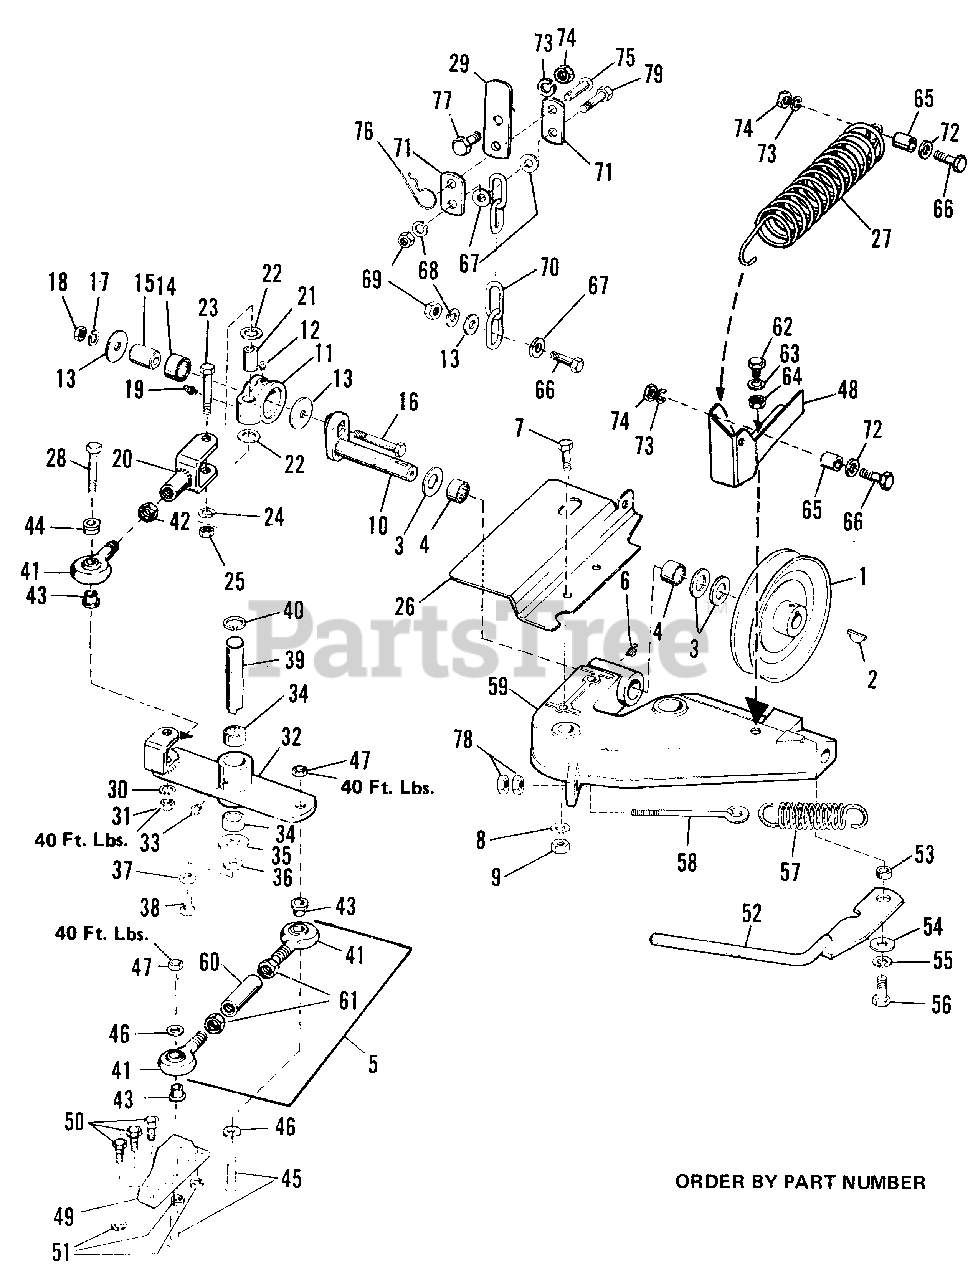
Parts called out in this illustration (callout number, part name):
1	Drive Pulley
2	Key, Hi-Pro
4	Bearing, Needle
5	Rod End Assembly
6	Fitting, Grease
7	Capscrew, Hex Hd., 3/8"-16 NC x 1-1/4" lg.
8	Lockwasher, 3/8"
9	Hex Nut, Full, 3/8"-16 NC
10	Shaft, Crank
11	Housing, Pitman Bearing
12	Fitting, Grease
13	Washer
14	Bearing, Needle
15	Race, Inner, Pitman Bearing
16	Capscrew, Hex Hd., 3/8"-16 NC x 2-1/4" lg.
17	Lockwasher, 3/8"
18	Hex Nut, Full, 3/8"-16 NC
19	Fitting, Grease (45ø)
20	Clevis Assembly, Pitman
21	Bearing, Pivot Block
23	Capscrew, Hex Hd., 3/8"-16 NC x 2-1/4" lg.
24	Lockwasher, 3/8"
25	Hex Nut, Full, 3/8"-16 NC
28	Capscrew, Hex Hd., 3/8"-16 NC x 2-1/2" lg.
29	Chain Support
30	Lockwasher, 3/8"
31	Hex Nut, Full, 3/8"-16 NC
32	Rocker Arm Assembly
33	Fitting, Grease
34	Bearing, Needle
36	Washer, Plain, 3/8"
37	Lockwasher, 3/8"
38	Capscrew, Hex Hd., 3/8"-16 NC x 3/4" lg.
39	Shaft, Rocker Arm
40	Ring, Retaining
42	Hex Nut, Full, 1/2"-20 NF
45	Hex Capscrew, 3/8"-24 x 1-3/4" lg.
47	Hex Nut, Full, Lock, 3/8"-24 NF
48	Mounting Assembly Cable
49	Head, Sickle
50	Capscrew, Hex Hd., 5/16"-24 NF x 3/8" lg.
51	Lockwasher, 5/16"
52	Latch Assembly
53	Spacer, Latch
54	Washer, Plain
55	Lockwasher, 7/16"
56	Capscrew, Hex Hd., 7/16"-14 NC x 1-1/4" lg.
60	Pivot End Rod
61	Jam Nut, Hex 1/2"-20 NF
62	Capscrew, Hex Hd., 7/16"-14 NC x 1" lg.
63	Lockwasher, 7/16"
64	Hex Nut, Full
66	Capscrew, Hex Hd., 3/8"-16 NC x 1" lg.
67	Washer, Plain, 3/8"
68	Lockwasher, 3/8"
69	Hex Nut, Full, 3/8"-16 NC
70	Chain, Lift
71	Link, Mower Lift
72	Washer, Plain, 3/8"
73	Lockwasher, 3/8"
74	Hex Nut, Full, 3/8"-16 NC
76	Clip, Spring
77	Capscrew, Hex Hd., 3/8"-16 NC x 1" lg.
78	Hex Nut, Full, 5/16"-18 NC
79	Capscrew, 3/8"-16 x 1-1/4"
